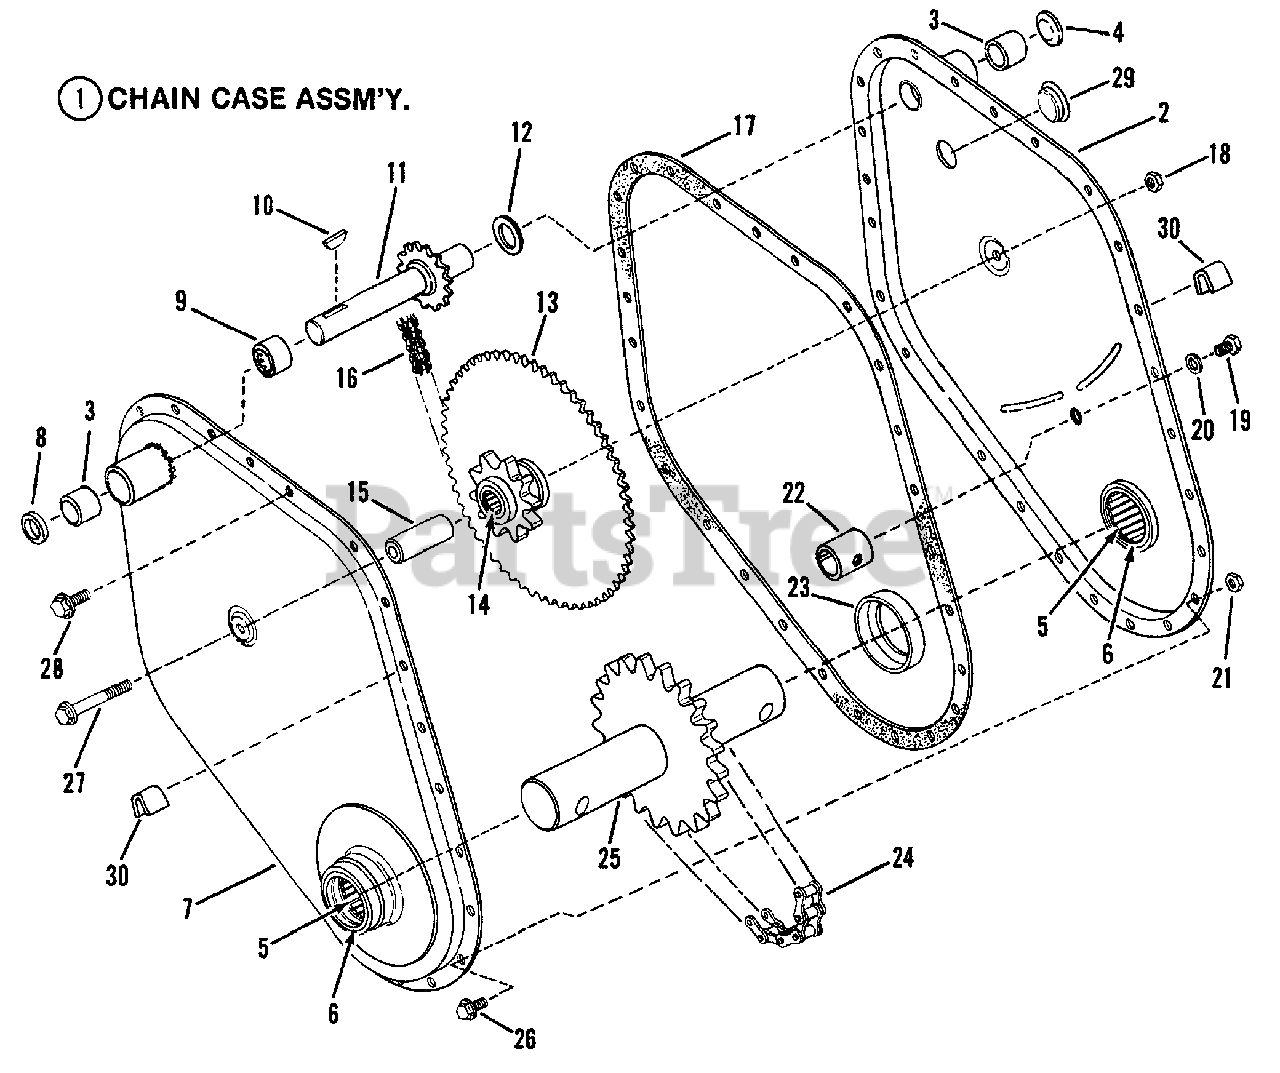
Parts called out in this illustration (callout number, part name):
1	CHAIN CASE ASY.
2	CASE ASY., R.H.
3	BEARING, Bronze .627" ID x .815" OD x .755" Wide
4	PLUG, Welch
5	BEARING, Needle 1.250" ID x 1.0" OD x 1.50" Wide
6	* SEAL, Oil 1.25" ID x 1.696" OD
7	CASE ASY., L.H.
8	SEAL, Drive Shaft .625" ID x .942 OD
9	SPACER, Drive Shaft
10	KEY, 3/16 x 3/4" Woodruff
11	SHAFT, Drive
12	WASHER, Shim
13	SPROCKET, Intermediate Asy.
14	SEAL, Drive Shaft .625" ID x .942 OD
15	RACE, Sprocket Bearing
16	CHAIN, Primary Drive
17	GASKET, Case Housing
18	NUT, 5/16-24 Hex Lock
19	HWST, 5/16C X3/8 ZP
20	WASHER, Seal
21	NUT, 5/16-24 Hex Center Lock
22	SPACER, Case Housings
23	SPACER, Rotor Shaft
24	CHAIN, Final Drive
25	SHAFT, Tine Rotor
26	SCREW, 5/16-24 x 5/8" Hex Head Cap, Grade 2
27	SCREW, 5/16-24 x 2-1/2" Hex Head Cap, Grade 5
28	SCREW, 5/16-18 x 5/8" Hex Washer Self-Tap
29	PLUG
30	SPACER, Case Housing to Rail
